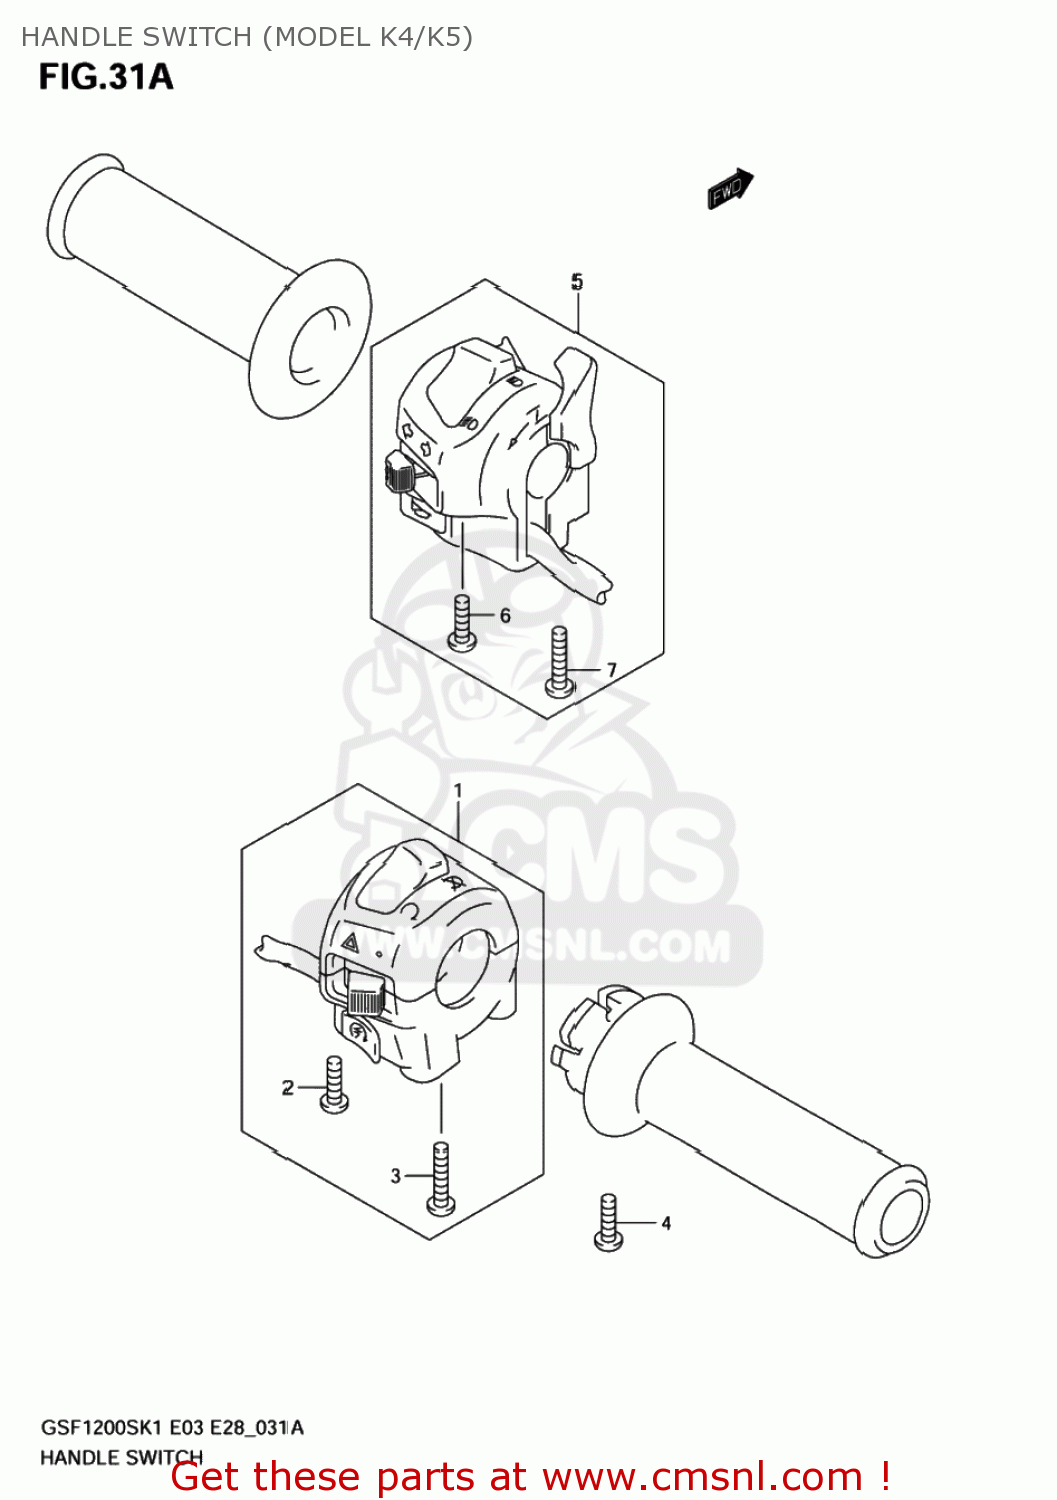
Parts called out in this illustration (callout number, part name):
1	SWITCH ASSY,HANDLE,R
2	SCREW
3	SCREW
4	SCREW
5	SWITCH ASSY,HANDLE,L
6	SCREW
7	SCREW
